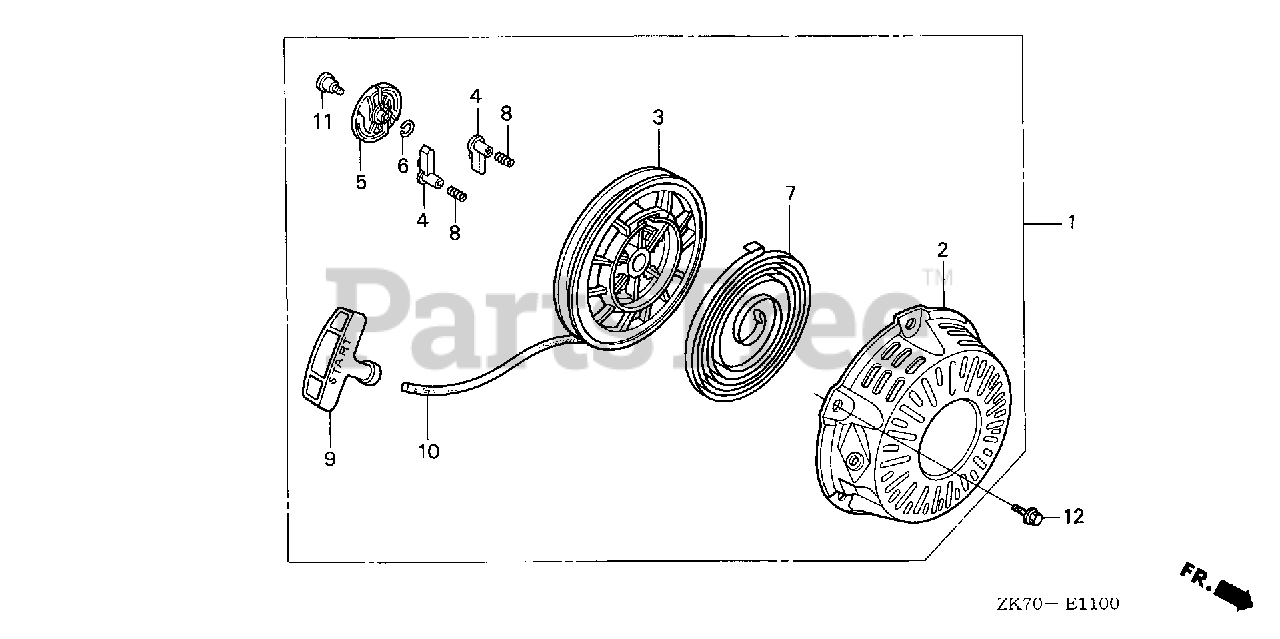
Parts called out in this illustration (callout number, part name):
1	STARTER ASSY., RECOIL *NH1* (BLACK)
2	CASE, RECOIL STARTER *NH1* (BLACK)
3	REEL, RECOIL STARTER (NATURAL)
4	RATCHET, STARTER
5	GUIDE, RATCHET
6	SPRING, FRICTION
7	SPRING, RECOIL STARTER
8	SPRING, RETURN
9	GRIP, STARTER
9	KNOB, RECOIL SRARTER
10	ROPE, RECOIL STARTER
11	SCREW, SETTING
12	BOLT, FLANGE (6X10)
